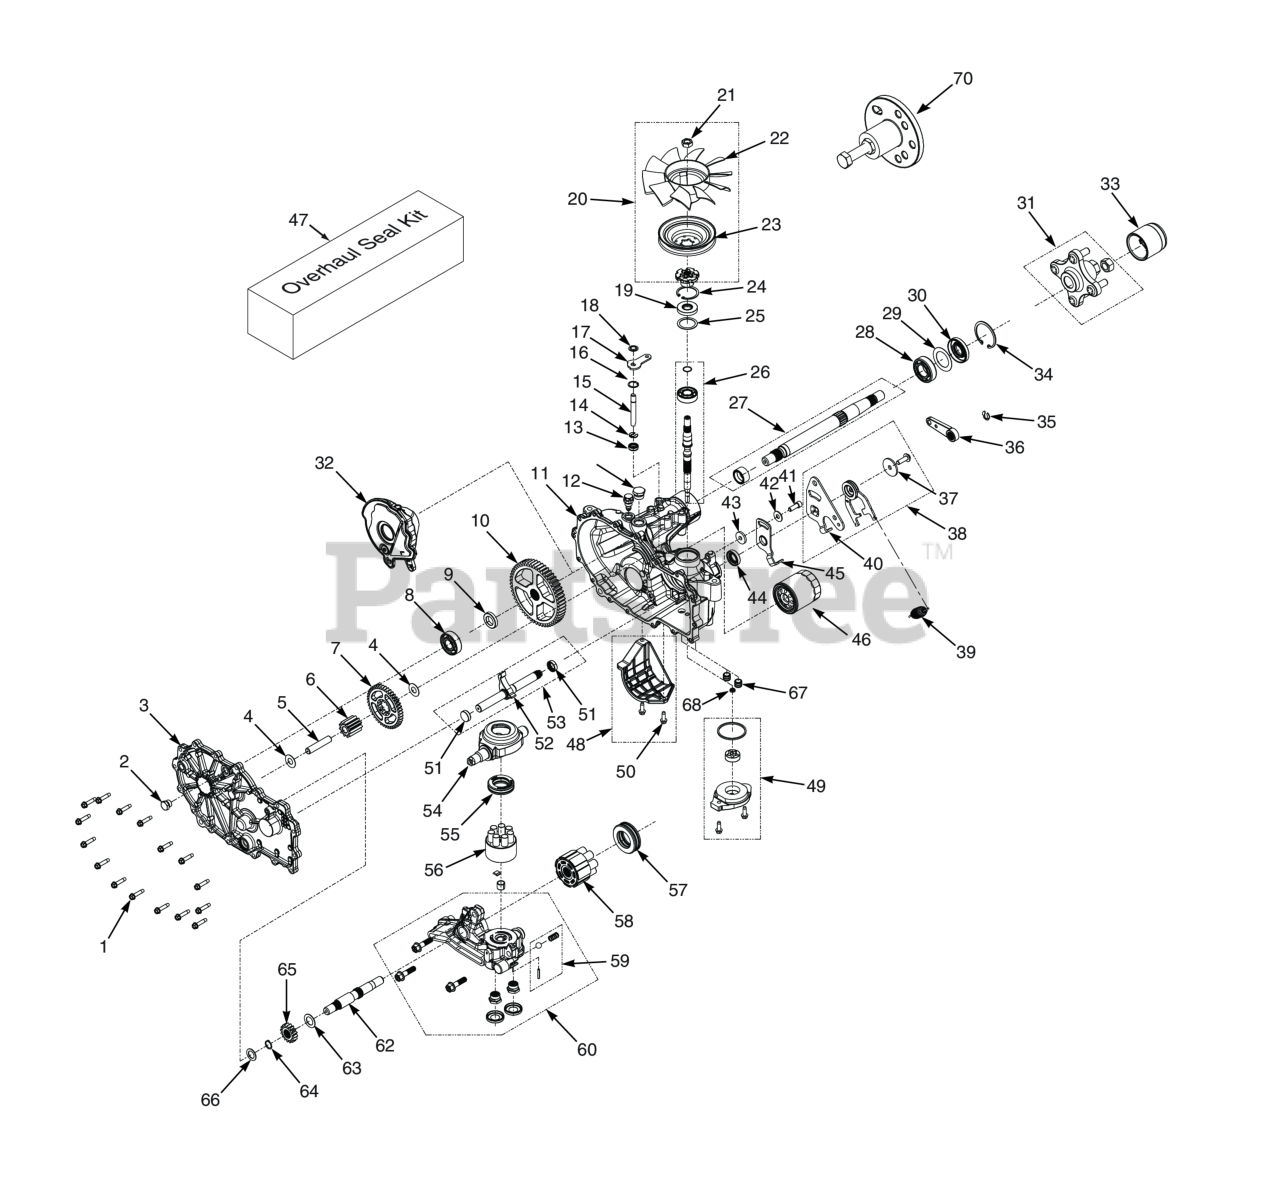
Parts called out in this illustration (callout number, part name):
1	Bolt, Hex Head 1/4-20 x 1-1/8"
2	Plug, External Hex Vent 9/16-18
3	Kit, Side Cover LH
4	Washer, .5 x 1.0 x .03
5	Jackshaft Pin
6	Gear, 11T
7	Gear, 43T
8	Kit, Bearing
9	Spacer, .750 x 1.320 x .257
10	Gear, 54T
11	Kit, Main Housing LH, Charge, Control
12	Fitting, Transmission - SFZ61
13	Seal, Lip .375 x .75 x .25
14	Ring, .Retaining .375 External
15	Rod, By-Pass
16	R i n g , Retaining .750 Internal
17	Arm, By-Pass
18	Ring, Retainging .375 External
19	Seal, Lip 17 x 40 x 7
20	Kit, Fan/Pulley
21	Nut, Hex Locking 1/2-20
23	Pulley
24	R i n g , Retaining 2.06 Internal
25	Washer, 1.23 x 1.56 x .04
26	Kit, Input Shaft
27	Kit, Shaft, Axle
28	Bearing, Ball 1.0 x 52 x 15 Open
29	Spacer, 1.355 x 2.035 x .021
30	Seal, Lip TC4 1.0 x 2.06 x .38
31	Hub Kit
32	Fitting 9 /16 - 18, Breather
33	Cap, Axle
34	R i n g , Retaining 2.06 Internal
35	Ring, Retaining External .375"
36	Handle, Brake
37	Washer, .343 x 1.5 x .062
38	Kit, RTN Assembly
39	Spring, RTN
40	Arm, Control
41	Bolt, Hex Head Cap Screw 5/16-24 x 1" Patch
42	Washer, 7/16 x 7/8 OD x .06 HT
43	Spacer, .32 ID x 1.005 OD x .1495 Thk
44	Seal, Lip 18 x 32 x 7
45	Arm, Neutral
46	Filter, Oil
47	Kit, Seal (ZT-2800)
48	Kit, Filter Guard (LH)
49	Kit, Charge Pump
50	Bolt, 1/4-20 x 3/4"
51	O-Ring, -111 x .103 x 424
52	Pawl, Brake
53	Kit, Outboard, RH Rot B / LH Rot A (LH)
54	Trunnion, Swashplate
55	Ball Thrust Bearing
56	Kit, Cylinder Block
57	Thrust Ball Bearing Assembly
58	Kit, 16cc Cylinder Block Assembly (steam
59	Kit, Charge Relief
60	Kit, Center Section
61	Screw, Hex Flange Head 3/8-16 x 1-1/2"
62	Shaft, Motor
63	Washer, .72 x 1.16 x .04
64	Ring, Retaining .625
65	Gear, 16T
66	Washer, HT .62 ID x 1.0 OD x .05 Thick
67	Tube, Charge Triple O-ring
68	Kit, Gerotor Seal
69	Plug, 3/4-16
70	Kit, Hub Puller
